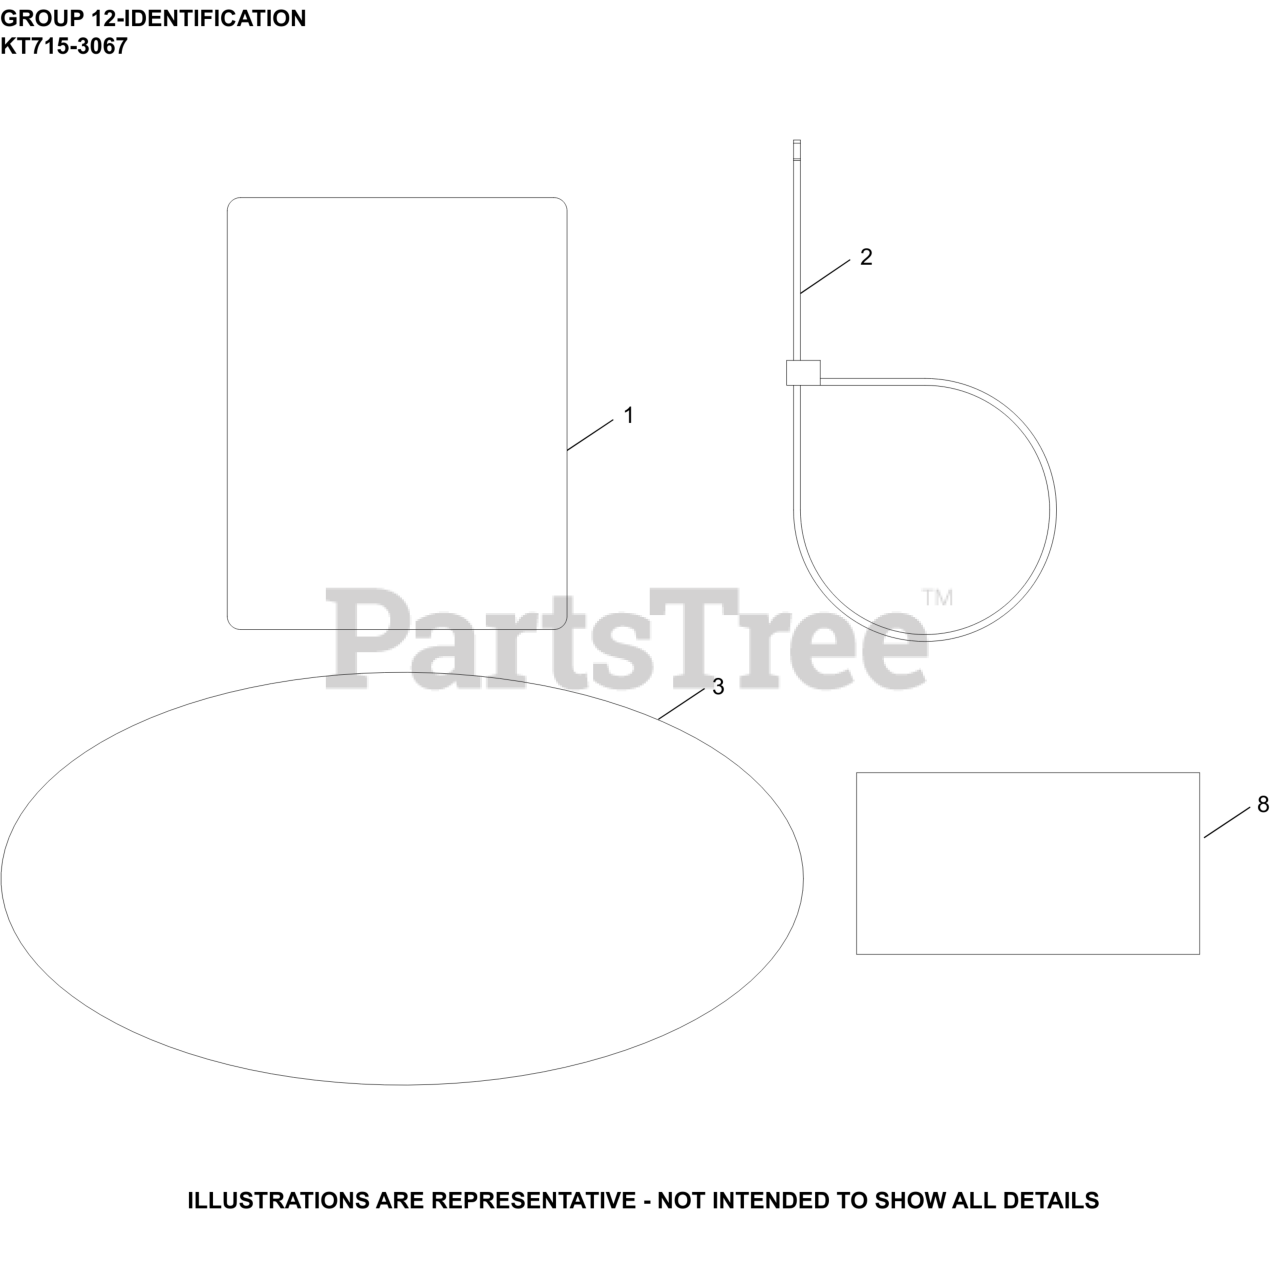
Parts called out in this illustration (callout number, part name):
1	LABEL, CLEAR LAMINATION
3	LABEL, 7000 SERIES (20HP, PRO)
8	DECAL, USA
